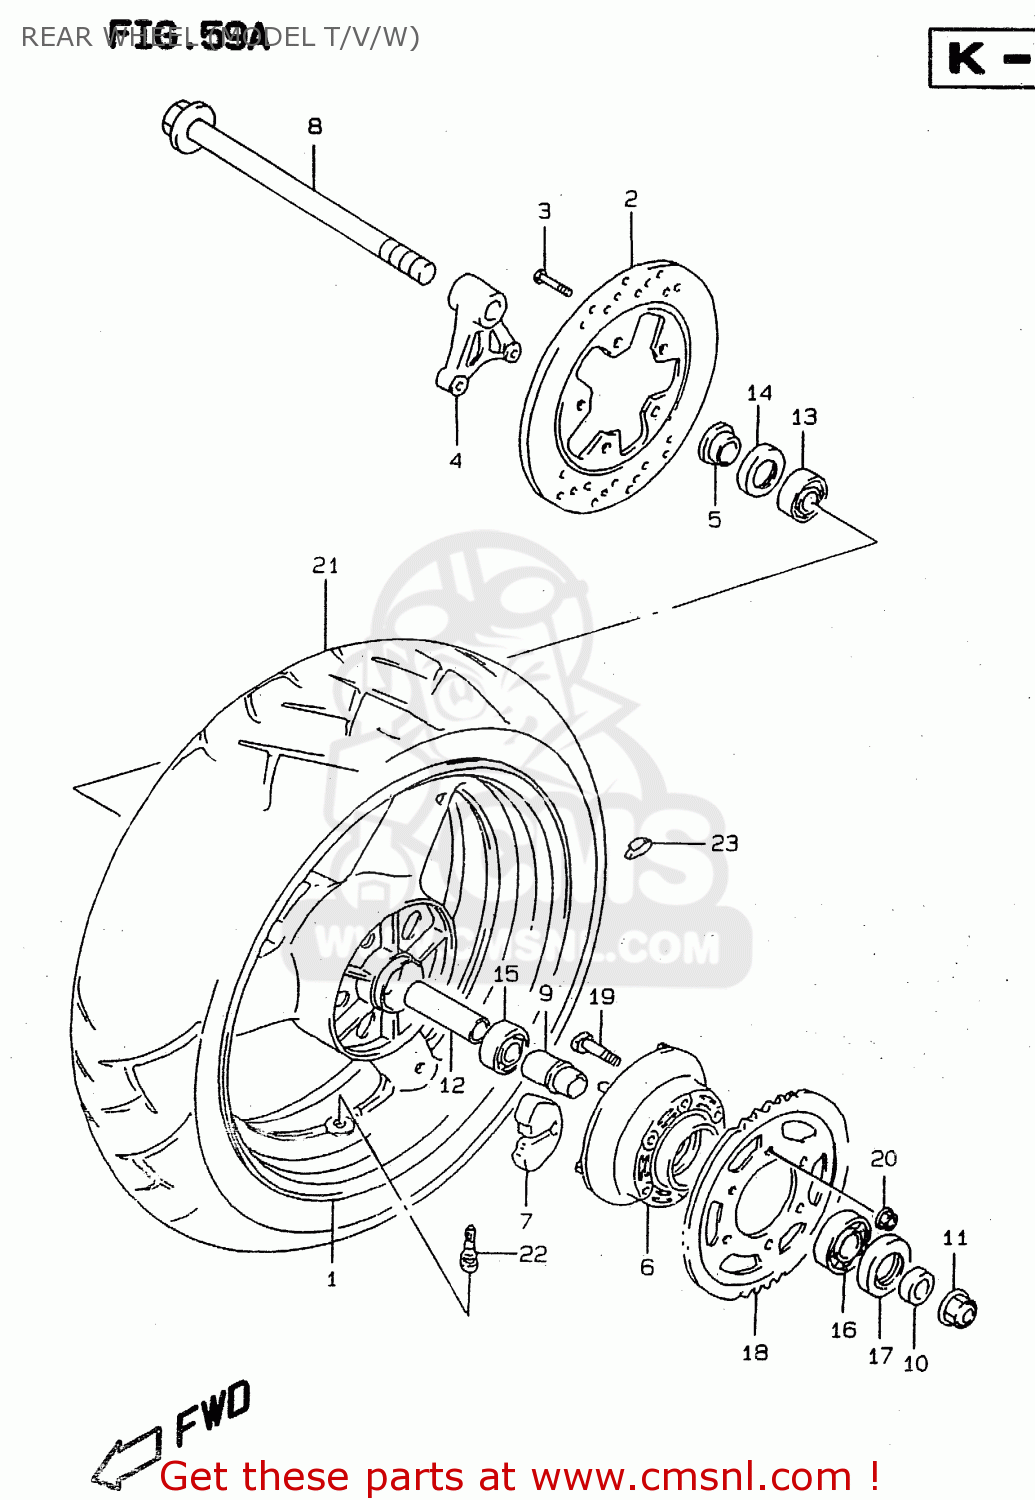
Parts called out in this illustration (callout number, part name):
1	WHEEL,REAR (MT5.50X17)(S
2	DISC,RR BRAKE
3	BOLT 8X33
4	BRACKET,RR CALIPER
5	SPACER,RR AXLE,R
6	DRUM,RR SPROCKET
7	ABSORBER,RR HUB SHOCK
8	AXLE,RR
9	RETAINER,RR HUB BEARING
10	SPACER,RR AXLE,L
11	NUT
12	SPACER,RR WHEEL HUB BEARING
13	BEARING(20X47X14)
14	SEAL,OIL(28X47X7)
15	BEARING(20X47X14)
16	BEARING(25X62X17)
17	SEAL,OIL(35X62X8)
18	SPROCKET,RR(NT:43)
19	BOLT
20	NUT
21	TIRE,REAR 170/60 ZR17
22	VALVE ASSEMBLY,WHEEL,TR412
23	BALANCER,WHEEL (10G)
